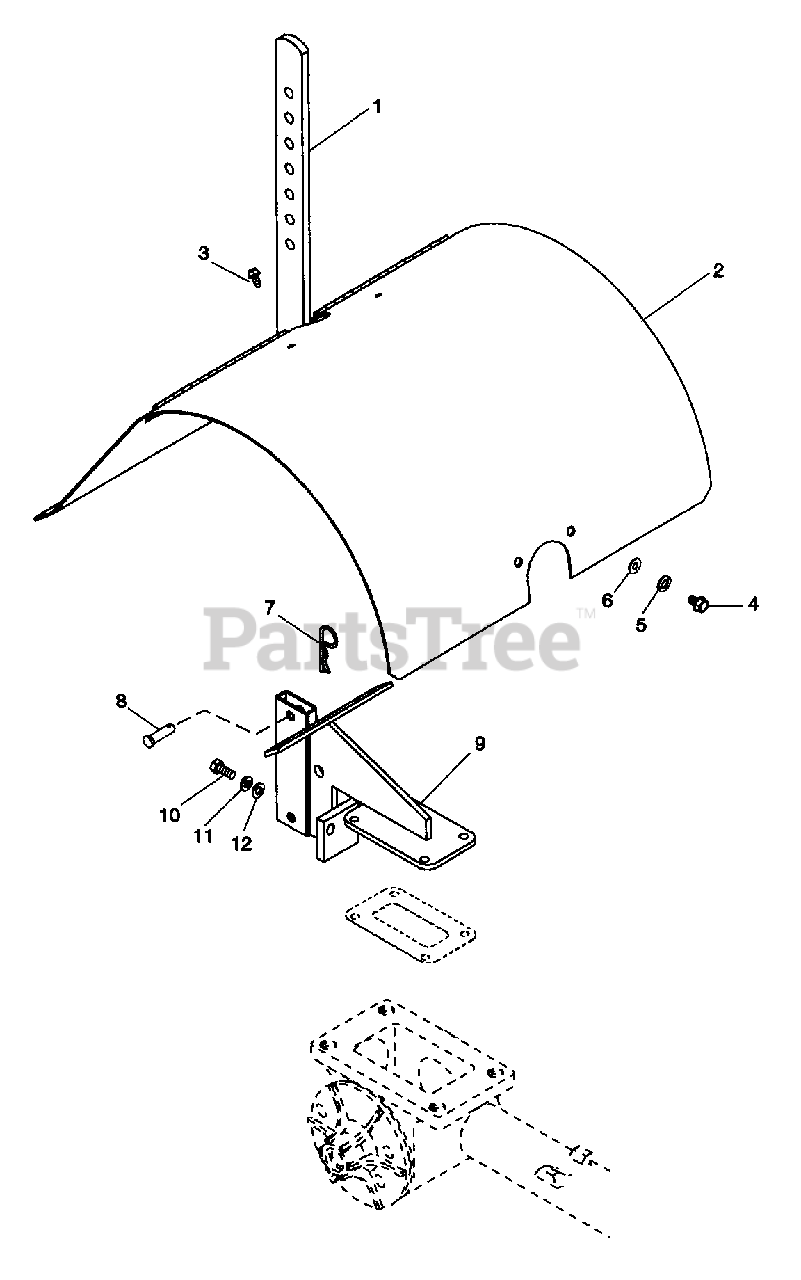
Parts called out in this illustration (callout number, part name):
1	DEPTH STICK
2	TINE HOOD W/ DECALS
3	SCR-TAP .250-20X.50 HXSLHDPL
4	BLT-HEX .31-18X.50
5	WSHR-LK-INT .313X.030 PL
6	WSHR-FL-STL.312X.734X.065PL
7	PIN-HAIR EXT .12X.31X2.37 PL
8	PIN-CLEV .372X1.25
9	DEPTH STICK HOLDER
10	BLT-HEX .31-18X.75 PL GR2
11	WSHR-LK .312X.097 PL HVY
12	WSHR-FL-STL .323X.625X.062 PL
